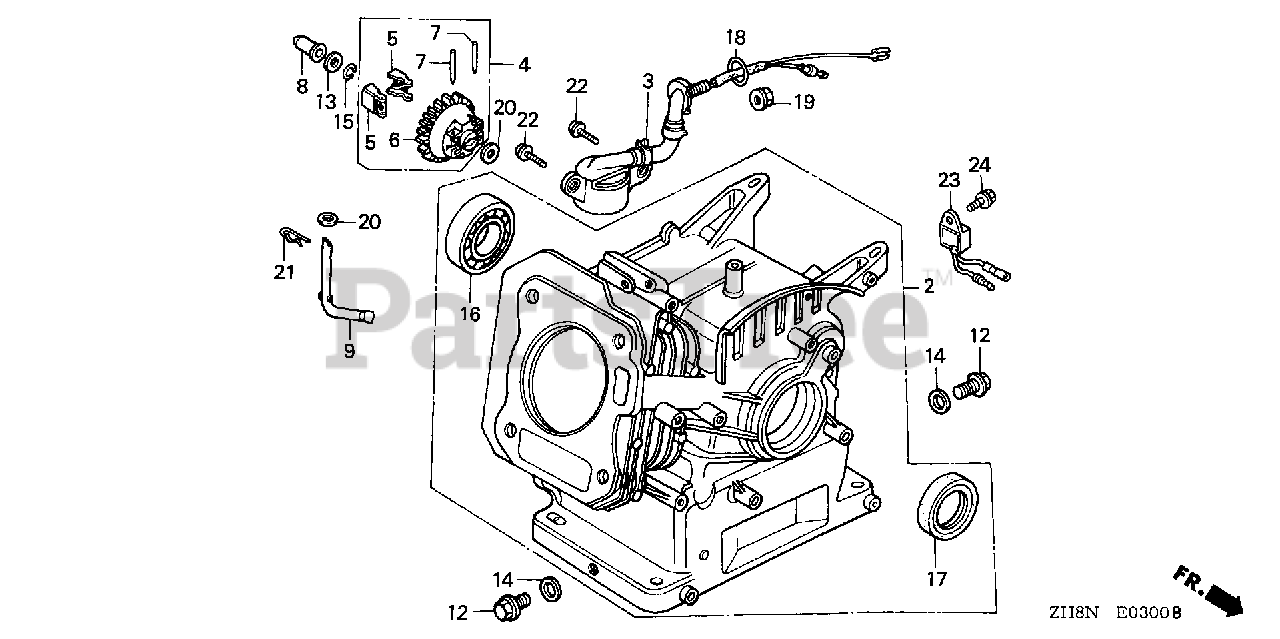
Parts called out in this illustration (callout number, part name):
2	CYLINDER ASSY. (811)
3	SWITCH ASSY., OIL LEVEL
4	GOVERNOR ASSY.
5	WEIGHT, GOVERNOR
6	HOLDER, GOVERNOR WEIGHT
7	PIN, GOVERNOR WEIGHT
8	SLIDER, GOVERNOR
9	SHAFT, GOVERNOR ARM
12	BOLT, DRAIN PLUG
13	WASHER, THRUST (6MM)
14	WASHER, DRAIN PLUG (10.2MM)
15	CLIP, GOVERNOR HOLDER
16	BEARING, RADIAL BALL (6205)
17	OIL SEAL (25X41X6)
18	O-RING (13.5X1.5) (ARAI)
19	NUT, FLANGE (10MM)
20	WASHER, PLAIN (6MM)
21	PIN, LOCK (8MM)
22	BOLT, FLANGE (6X12)
